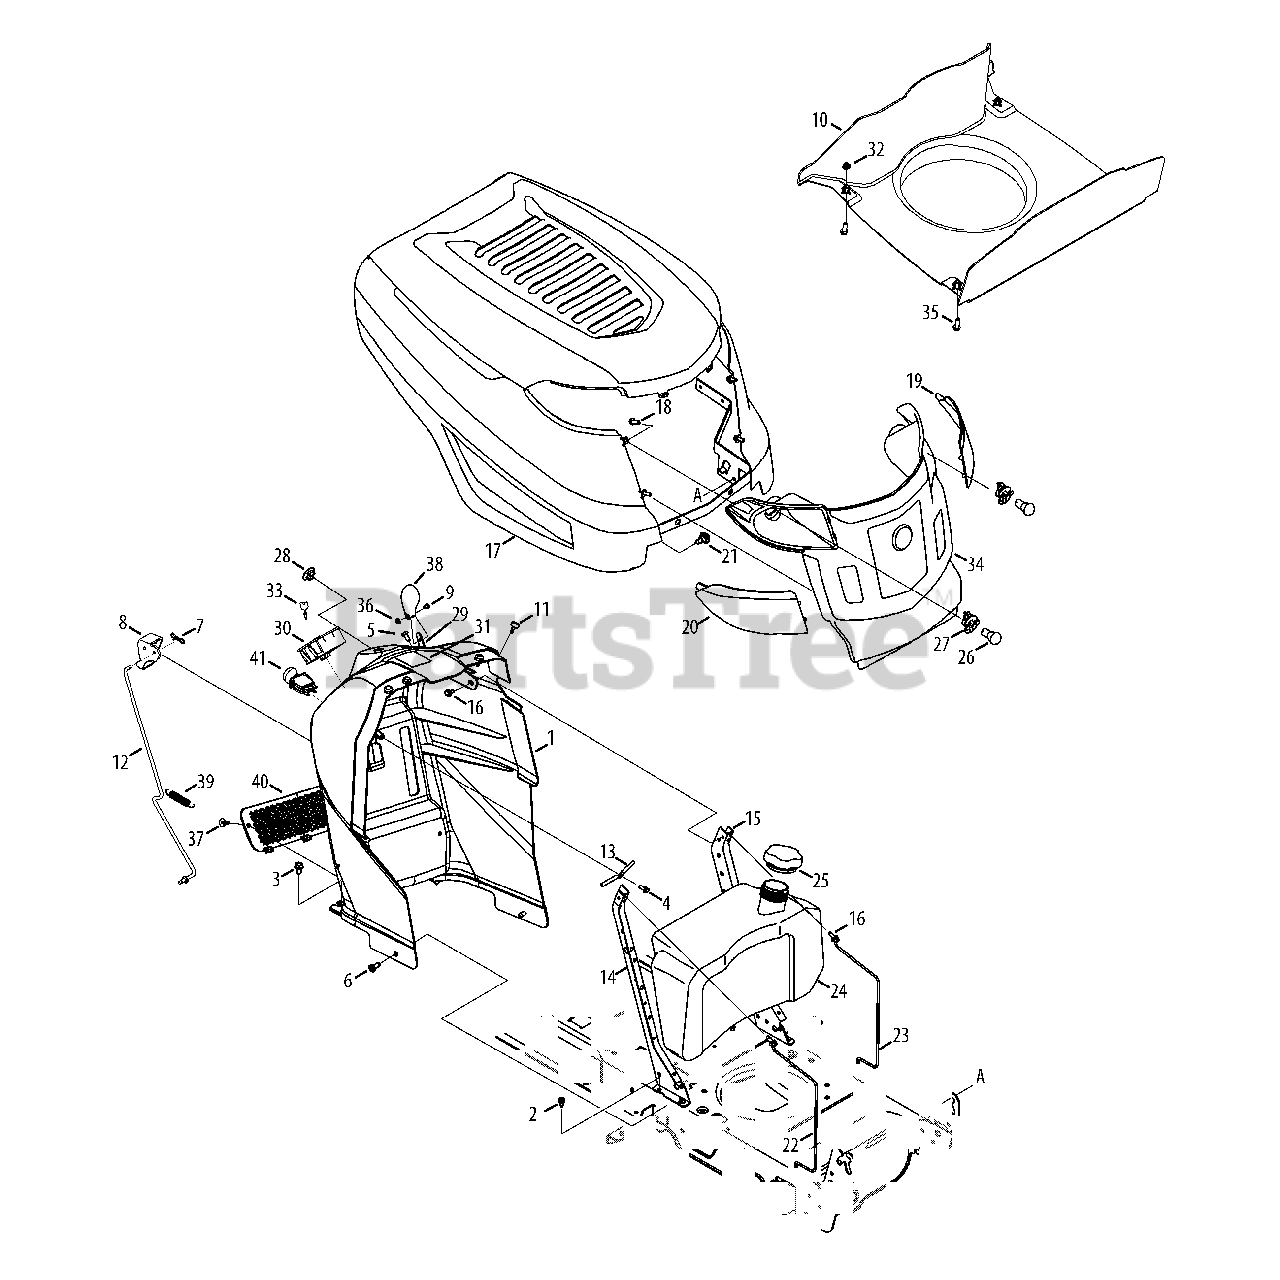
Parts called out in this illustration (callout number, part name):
2	Taptite Screw ,1/4-20:0.500
3	Taptite Screw ,5/16-18:.750
4	Hi-Lo Screw, 1/4-15:0.750
5	Screw, 1/4-14:0.625
6	Taptite Screw ,5/16-18:0.750
7	Bow Tie Cotter Pin
9	Machine Screw, #8-32:0.375
12	Control Rod Latch
14	RH Support Plate
15	LH Support Plate
16	Tap Screw, 1/4-20, 0.625
18	Screw, 1/4 DIA:.750
21	Shoulder Screw, .43 x .29
22	LH Tank Support Rod
23	RH Tank Support Rod
27	Lamp Socket
28	Choke Plug
29	Throttle/Choke Cable, 46.5"
30	Key Switch Module
31	Hour Meter
32	Flangelock Nut, 1/4-20
33	Key, Assembly
35	Hex Screw, 1/4-20:.620
36	Hex Nut, #8-32:GRA
37	Ratchet Clip:.250 DIA
38	Control Knob
39	Extension Spring, .500 DIA X 2.733 LG
40	Accessory Net
41	Electric PTO Switch
